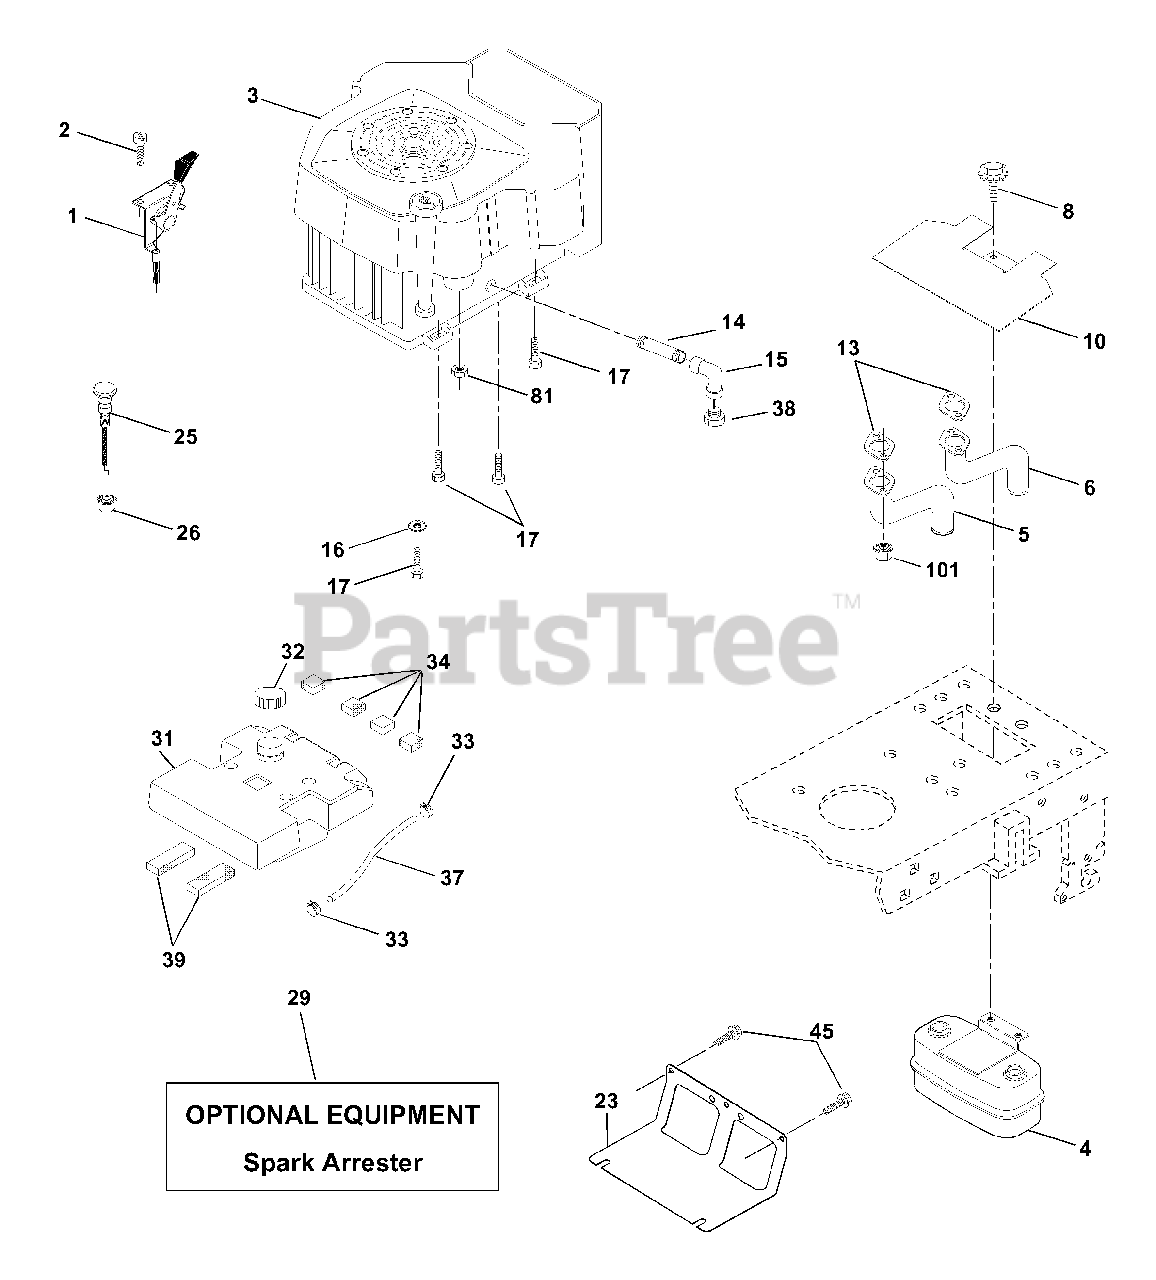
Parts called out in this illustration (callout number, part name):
1	Control Throt Flg 180 LH
2	Screw Hex Thd Cut 1/4-20x5/8 T
4	Muffler Asm Twin Lo-Tone
5	Pipe Exhaust CV18/20 LH
6	Pipe Exhaust CV18/20 RH
8	Bolt 5/16-18unc x 3/4 W/Sems
10	Shield Heat Muffler CV18/20
13	Gasket Kohler CV18-CV26
14	Nipple Pipe 3/8 Npt X 4-1/2"
15	Elbow Std 90 Degree 3/8-18 Npt
16	Washer Lock Ext Tooth 3/8
17	Screw Thdrol 3/8-16 x 1-1/2
23	Shield Browning
25	Choke Control 37"
26	Nut, Keps 3/8-24 Unf
29	Kit Spark Arrestor (Flat Scrn)
31	Tank Fuel 3 50 Rear
32	Cap Asm Fuel Top N/Lany Vented
33	Clamp Hose Blk
34	Pad, Spacer
37	Line Fuel 7.5
38	Plug Oil Drain
39	Pad, Idler
45	Screw 3/8-16 x 3/4
81	Nut Flange 1/4-20 Starter Nut
101	Nut Flange M8-1.25 Non-Lk Zinc
